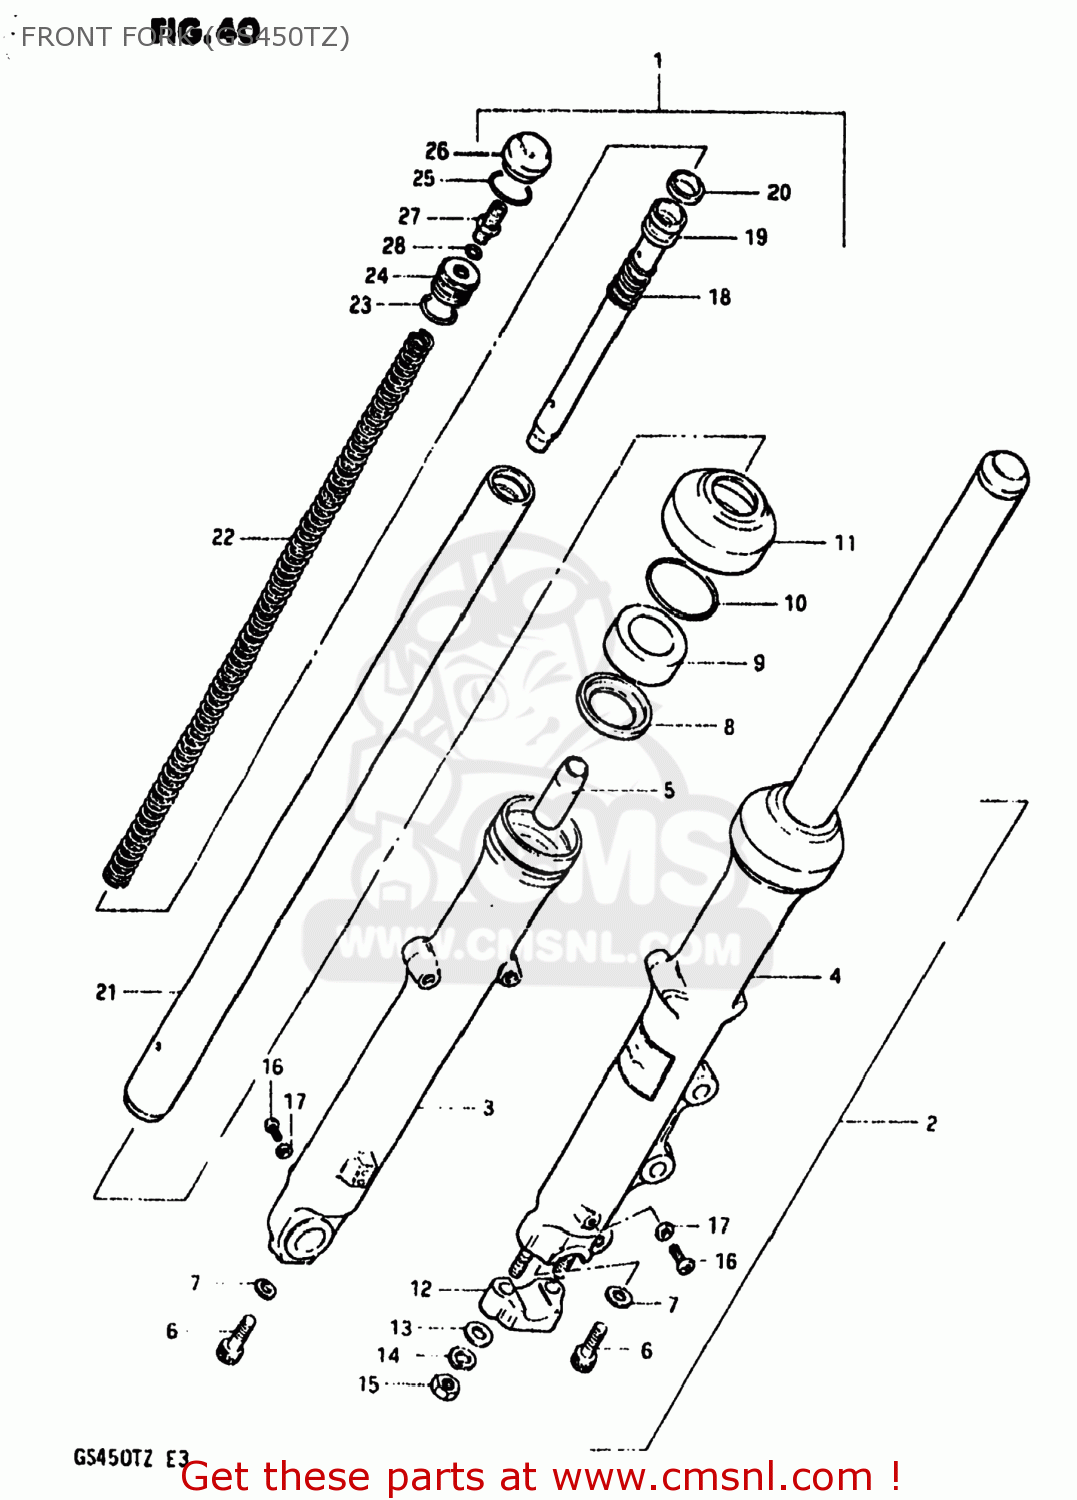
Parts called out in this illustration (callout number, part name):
1	DAMPER ASSEMBLY,RIGHT
2	DAMPER ASSEMBLY,LEFT
3	TUBE,FORK,OUTER,RIGHT
4	TUBE,FORK,LEFT,OUTER
5	PIECE,OIL LOCK
6	BOLT(8X27)
7	GASKET (NAS)
8	SPACER,OIL SEAL
9	OIL SEAL,FRONT FORK
10	RING,OIL SEAL STOPPER
11	DUST SEAL
12	HOLDER,AXLE
13	WASHER
14	LOCK WASHER
15	NUT (8MM)
16	SCREW 4X6
17	GASKET (NAS)
18	SPRING,REBOUND
19	CYLINDER,FRONT FORK
20	RING,PISTON
21	TUBE,FORK,INNER
22	SPRING
23	O RING
24	SEAT,SPRING
25	RING,STOPPER
26	CAP,FRONT FORK
27	VALVE,AIR
28	O-RING
